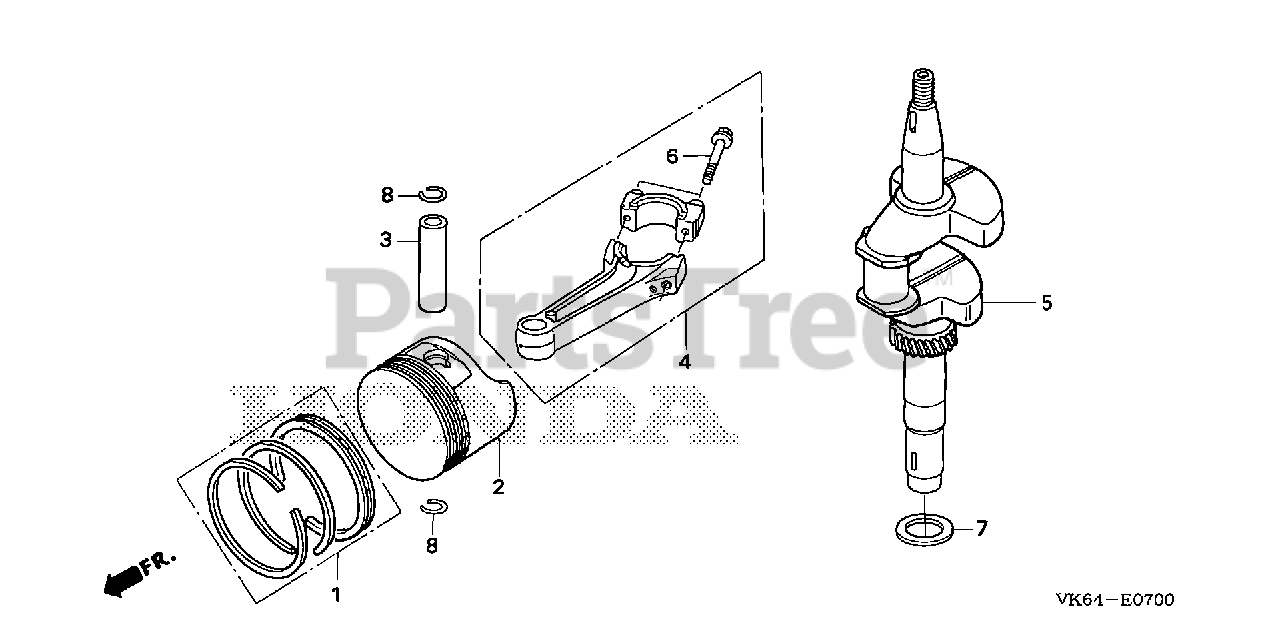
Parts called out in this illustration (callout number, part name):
1	RING SET, PISTON (STD) (TPR)
1	RING SET, PISTON (STD) (RIKEN)
2	PISTON (STD)
3	PIN, PISTON
4	ROD ASSY., CONNECTING (IDENT MARK Z)
4	ROD ASSY., CONNECTING
5	CRANKSHAFT
6	BOLT, CONNECTING ROD (IDENT MARK Z)
7	WASHER, THRUST (25.6MM)
8	CLIP, PISTON PIN (18MM)
